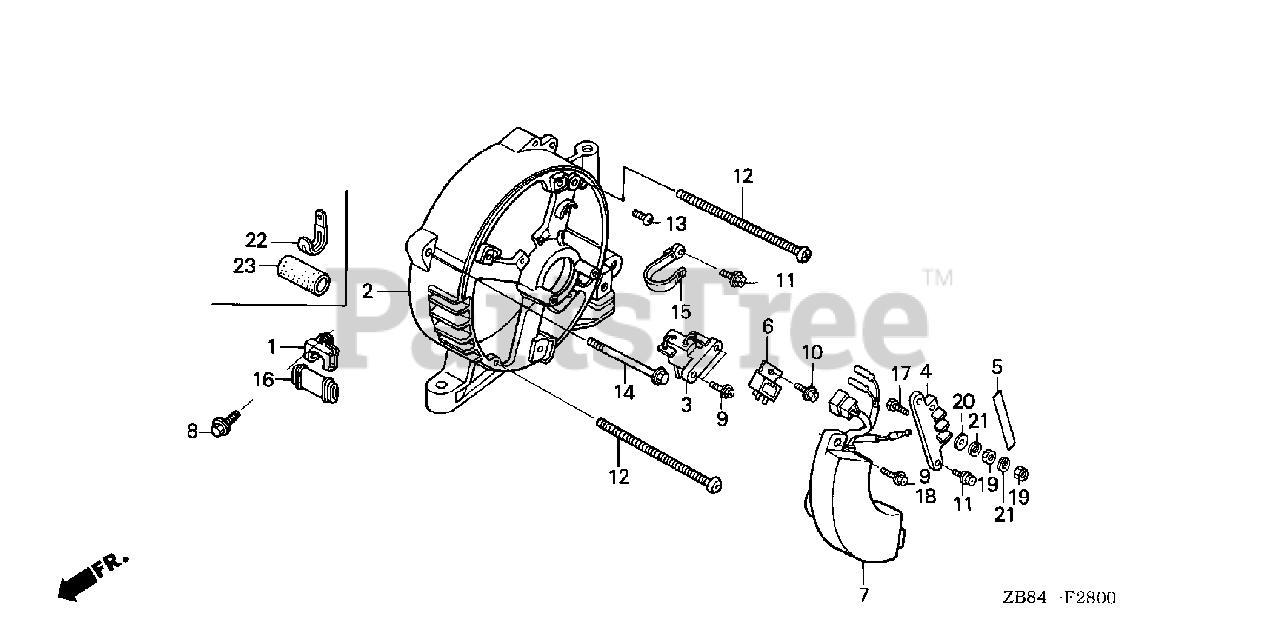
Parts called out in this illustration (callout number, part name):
1	CLIP, WIRE
2	HOUSING, RR.
3	BRUSH ASSY.
4	TERMINAL, VOLT CHANGE
5	MARK, VOLT
6	DIODE, D.C.
7	REGULATOR ASSY., AUTOMATIC VOLTAGE
8	BOLT, FLANGE (6X12) (CT200)
9	SCREW, TAPPING (5X18)
10	SCREW, TAPPING (5X12)
11	SCREW, TAPPING (5X14)
12	SCREW, PAN (5X195)
13	SCREW, PAN (5X12)
14	BOLT, FLANGE (6X160)
15	TIE, CABLE
16	TUBE, CORD
17	BOLT, HEX. (5X20)
18	SCREW, TAPPING (5X16)
19	NUT, HEX. (5MM)
20	WASHER, PLAIN (5MM)
21	WASHER, SPRING (5MM)
22	CLIP, WIRE HARNESS
23	TUBE, WIRE
